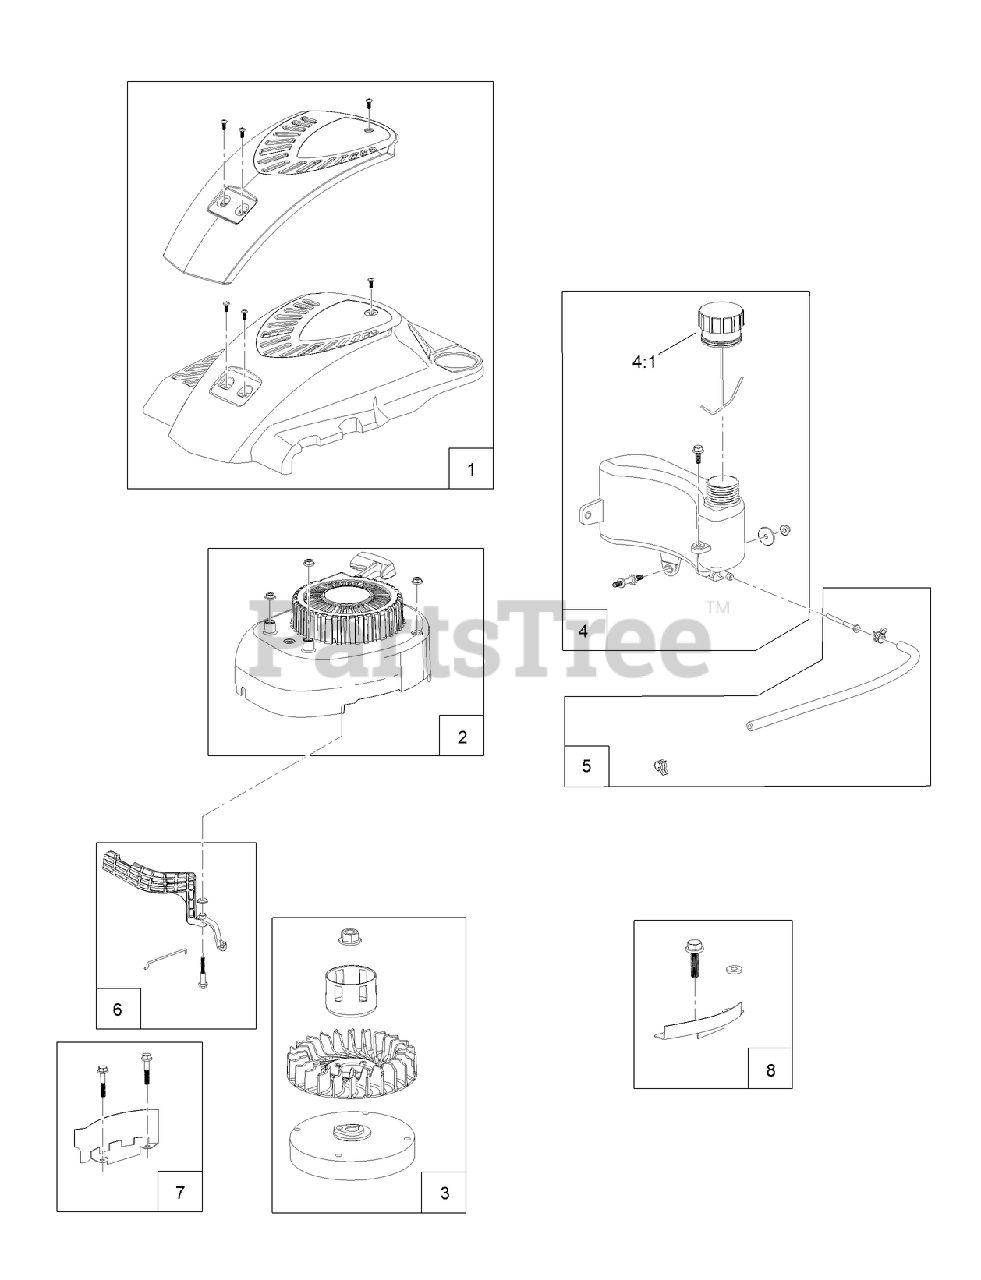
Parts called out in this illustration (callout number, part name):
1	SHROUD ASM
2	RECOIL AND BLOWER SHROUD KIT
3	FLYWHEEL AND FAN KIT
4	FUEL TANK KIT
4:1	CAP-FUEL
5	FUEL LINE KIT
6	AIR VANE KIT
7	FLYWHEEL SHIELD KIT
8	FLYWHEEL GUARD KIT
